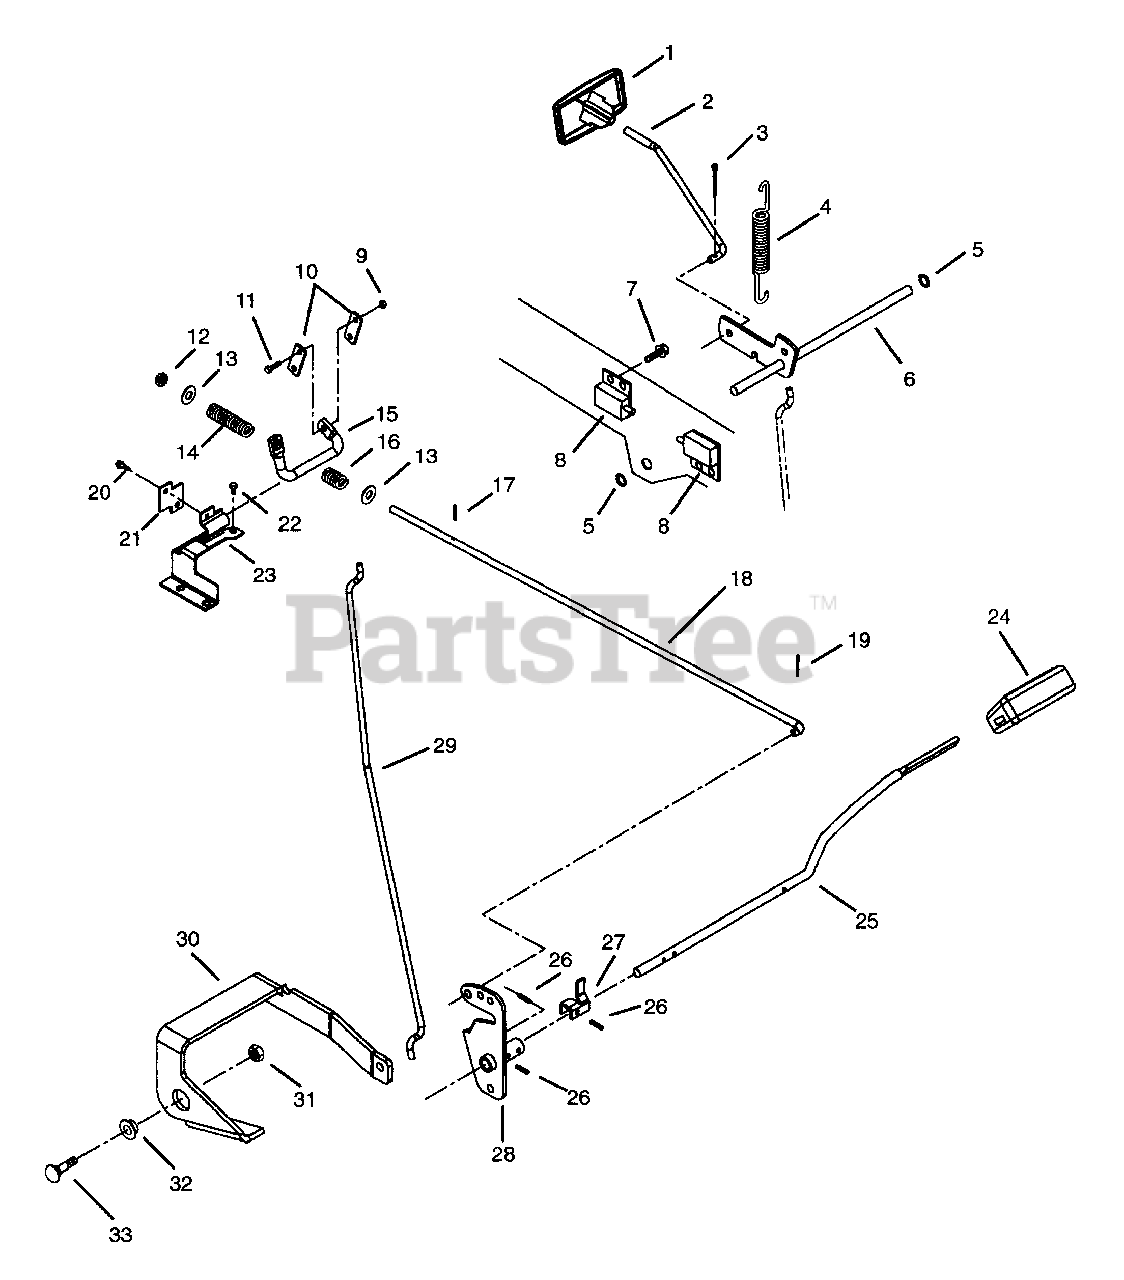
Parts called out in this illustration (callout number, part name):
1	KNOB- PARK BRAKE
2	ROD, PARKING BRAKE
3	PIN-COTR .06X.50
4	SG-TENS .051X.60X2.25 WLD 7.0
5	RG-RTNG-EXT .250X.010
6	BELLCRANK-PARKING BRAKE
7	SCR-TAP 12-24X.50 HWH PL TR
8	SWITCH- SINGLE POLE N.O.
9	NUT-LK-NYL .250-20 PL
11	BLT-HEX .25-20X1.00 PL GR5
12	NUT-LK-CTR .375-16 GR A PL
13	WSHR-FL-STL.406X.812X.065PL
14	SG-COMP 2.00X.404
15	ROD, BRAKE PIVOT
16	SG-COMP .62X.68X1.75
17	PIN-ROLL .125X.75
18	ROD, BRAKE
19	PIN-COTR .09X.75 PL
20	SCR-TAP .250-20X.37 HWH PL TR
21	PLATE, HOLDING
22	BLT-HEX .31-18X.50 GR5
23	BRACKET, BRAKE ROD PIVOT
24	COVER - PEDAL - BRAKE
25	PEDAL - BRAKE
26	PIN-GRV .188X1.25 TP A
27	LEVER - BRAKE SWITCH
28	ARM & HUB - BRAKE
29	ROD, PARKING BRAKE
30	LEVER, PARKING BRAKE
31	NUT-LK .312-18 GR A PL
32	BSHG, FLG .325X.499X.26X.88
33	BLT-RDHDSQNK.31-18X.75GR5SHTPL
